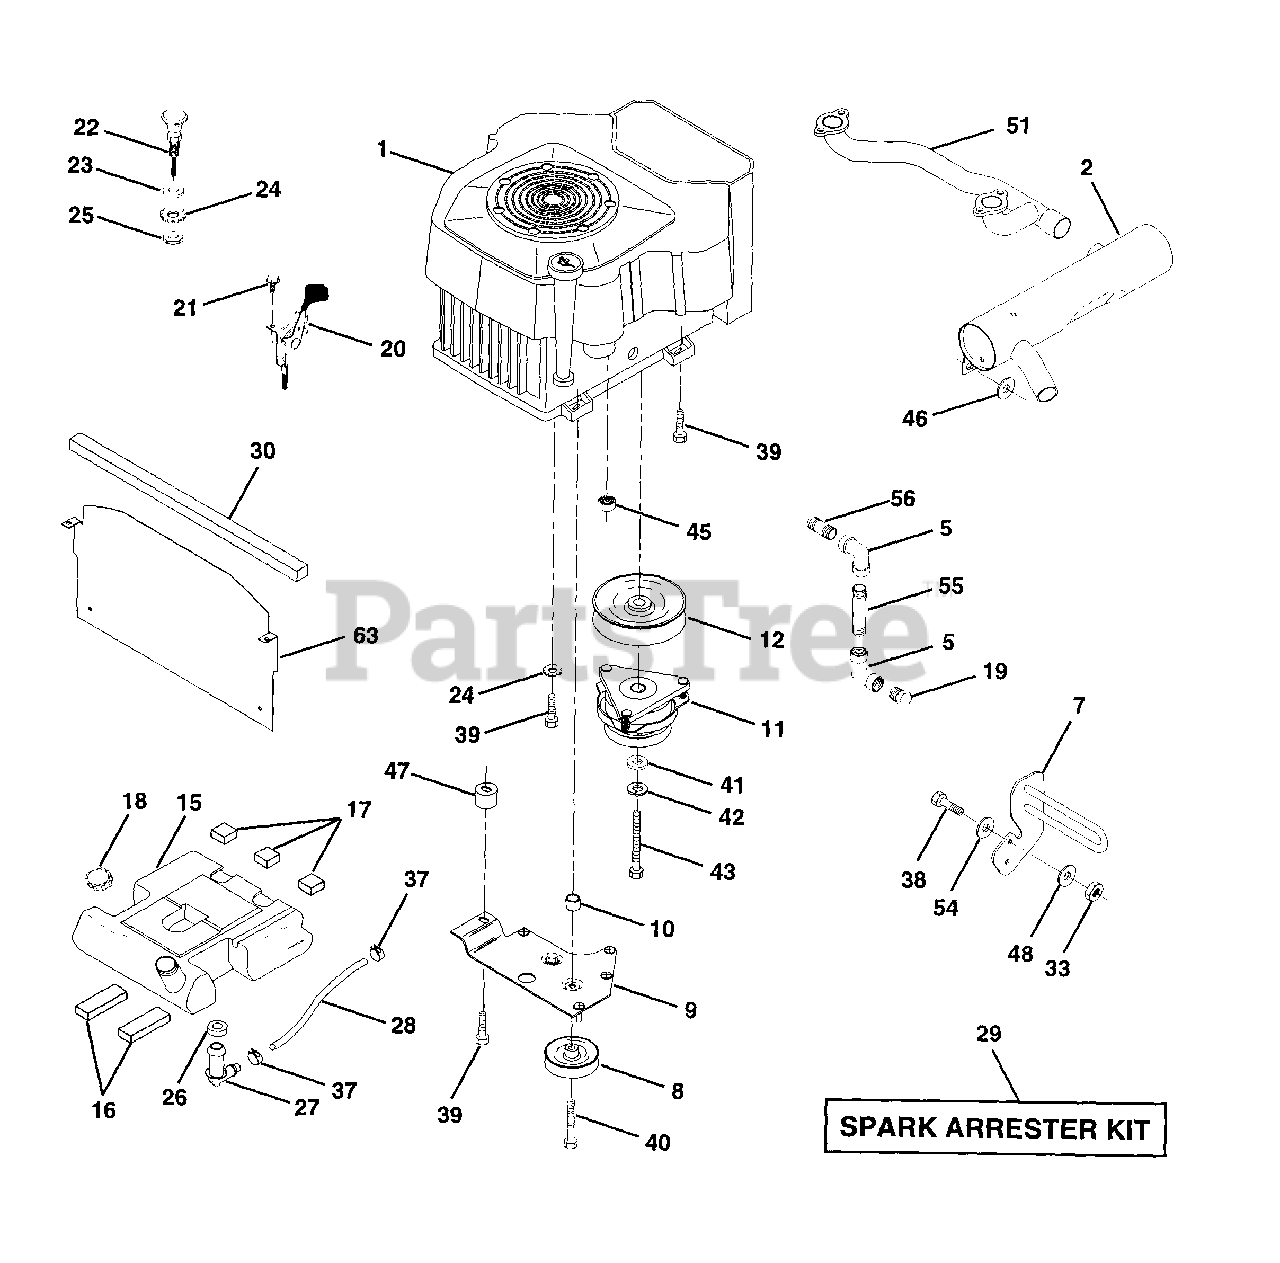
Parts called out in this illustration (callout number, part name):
2	Muffler VGT Cylinder
5	Elbow STD 90 Degree 3/8-18 NPT
7	Muffler Assembly Guard
8	Pulley V-Idler
9	Stop Keeper Asm VGT
11	Clutch Electric
12	Pulley Engine VGT Elect Clutch
15	Tank Fuel W/Sym Vented
16	Pad Spacer
17	Pad Spacer
18	Cap Asm Fuel W/Sym Vented
19	Plug Oil Drain (Order From Engine Manufacturer)
20	Control Throttle
21	Screw Hex Thd Cut 1/4-20 X 5/8
22	Control Choke
23	Washer 13/32 X 13/16 x 16 Ga
24	Washer Ext Tooth 3/8
25	Nut Fin Hex 3/8 - 24 UNF
26	Bushing
27	Stem Tank Fuel
28	Fuel Line
29	Spark Arrester Kit
30	Strip Foam 18"
33	Nut, Hex W/Ins. 3/8-16 UNC
37	Clamp Hose
38	Bolt, Fin Hex 3/8-16 UNC x 1-1/2
39	Screw TT 3/8-16 x 2-1/4 UNC
40	Screw TT 3/8-16 x 4 UNC
41	Washer 1-1/2 OD X 15/32 ID X .250
42	Washer Lock 7/16
43	Bolt Hex 7/16-20 X 4-1/4 Ga 5
45	Nut Flange 1/4-20 Starter Nut
46	Washer 13/32 x 1 x 16 Ga.
47	Spacer Engine
48	Washer 13/32 x 1-1/4 x 7 Ga.
51	Pipe Crossover
54	Washer Flat 13/32 x 7/8 x 14 Ga.
55	Nipple, Pipe 3/8 NPT x 4-1/2
56	Nipple, Pipe 3/8 NPT x 1.00
63	Shield, Heat VGT YP/Husq.
